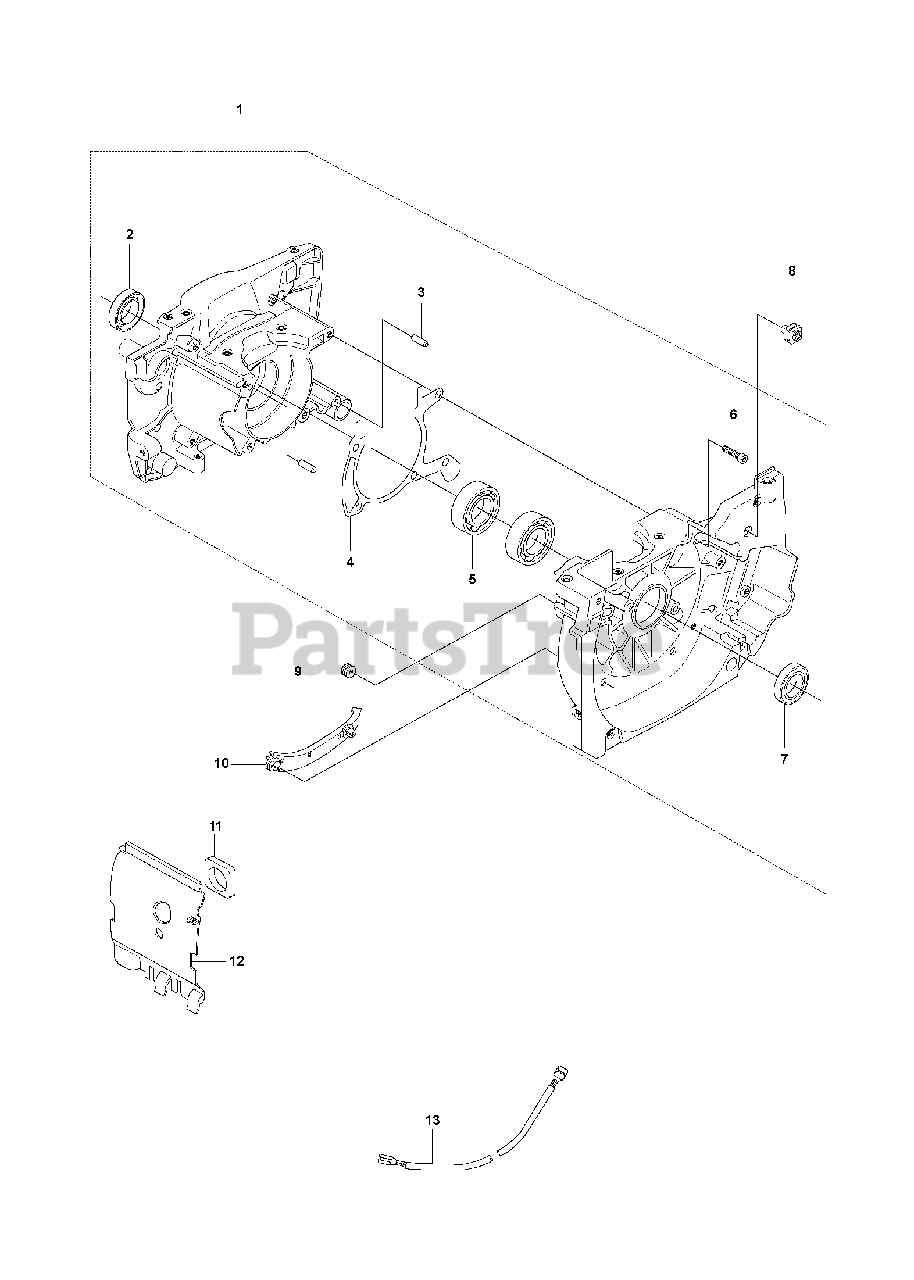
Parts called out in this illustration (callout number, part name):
1	CRANKCASE
2	SEALING RING
3	PIN 5X14
4	GASKET
5	BALL BEARING-6202-C3 SKF
6	SCREW MC6S 5X20
7	SEAL RING
8	CABLE SOCKET
9	FUEL TANK BUSHING
12	AIR CONDUCTOR
13	SHORTING LEAD
